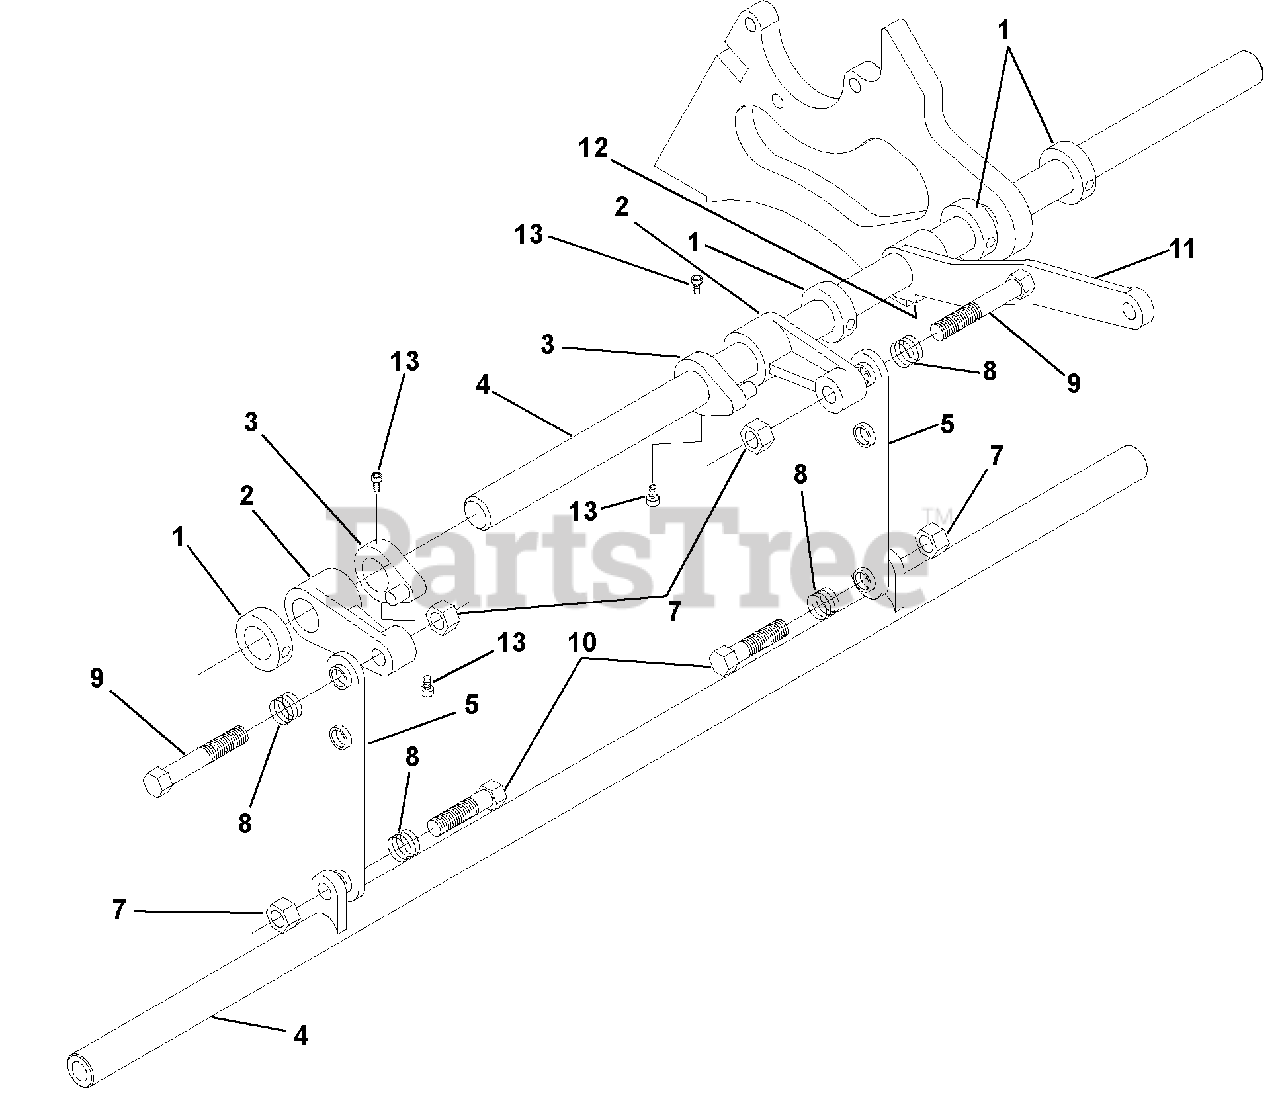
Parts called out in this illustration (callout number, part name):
2	Arm,Reel Lift
3	Collar,Lift
4	Shaft,Lift 30-inch
5	Bar, Spacer 30-Inch
7	Nut,Hex .38-16
9	Cap Screw Hex Head .38-16 x 1.75
10	Cap Screw Hex Head .38-16 x 1.50
11	Lever, Reel Lift
12	Set Screw, Socker .312-24 x .25 Stainless Steel
13	Set Screw, Hex Socket Head .25 x .38 Grade 8
